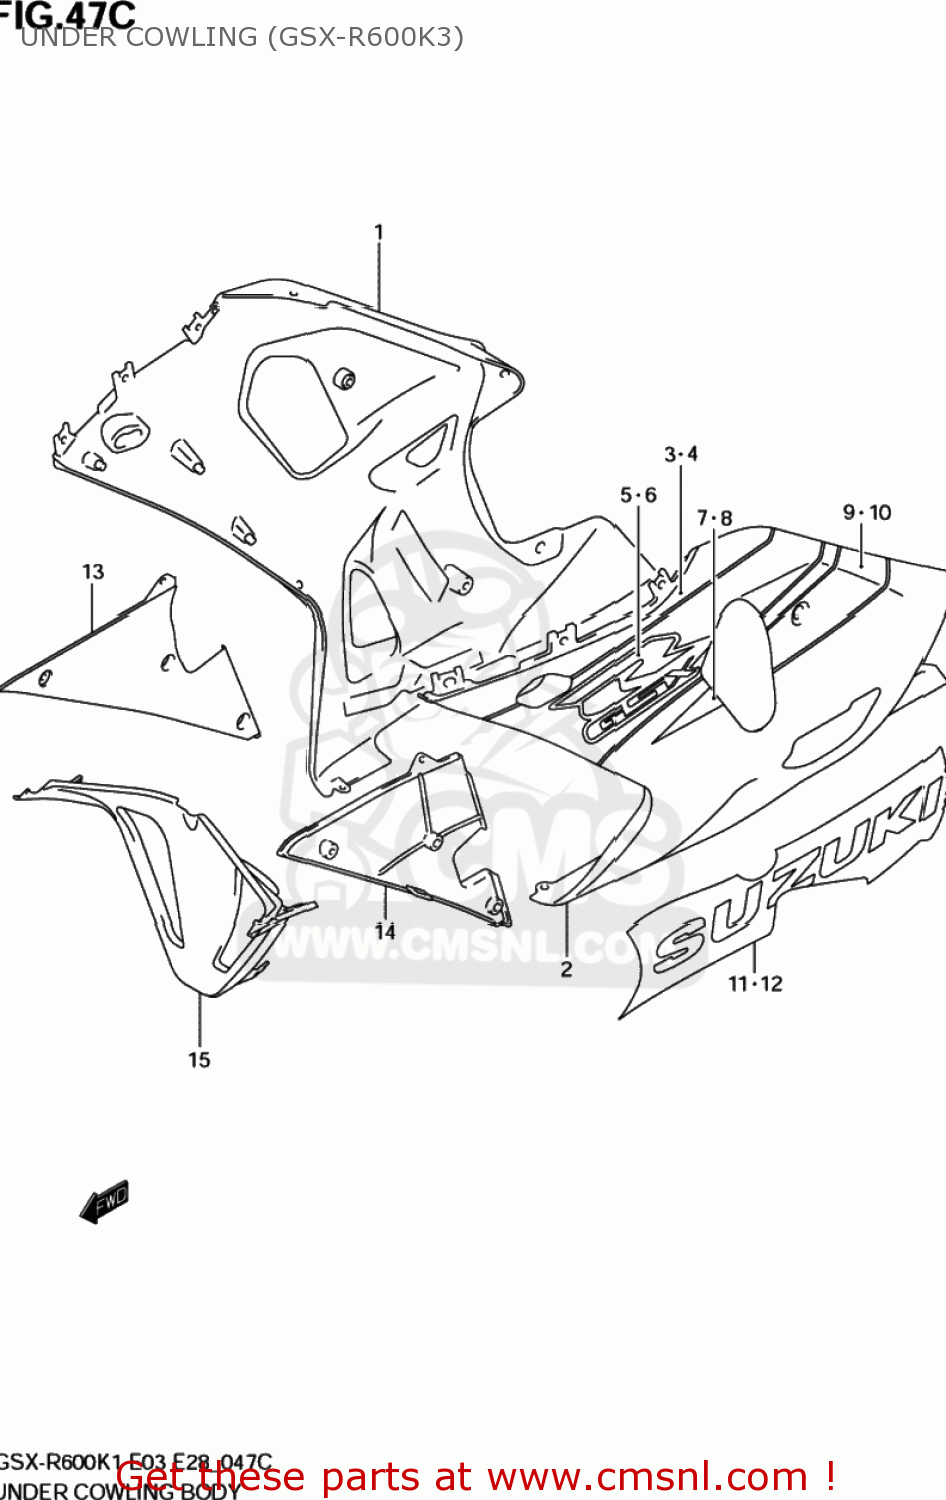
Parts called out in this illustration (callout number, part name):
1	COWLING ASSY,UNDER,R
2	COWLING ASSY,UNDER,L
3	TAPE SET,COWL UNDER UPR,R
4	TAPE SET,COWL UNDER UPR,L
5	TAPE
6	TAPE,COWL UNDE
7	TAPE,COWL UNDER,R
8	TAPE,COWL UNDER,L
9	TAPE,COWL UNDER MIDDLE,R
10	TAPE,COWL UNDER MIDDLE,L
11	TAPE SET,COWL
12	TAPE SET,COWL
13	COWLING,UNDER INNER,R
14	COWLING,UNDER INNER,L
15	COWLING,UNDER CTR
